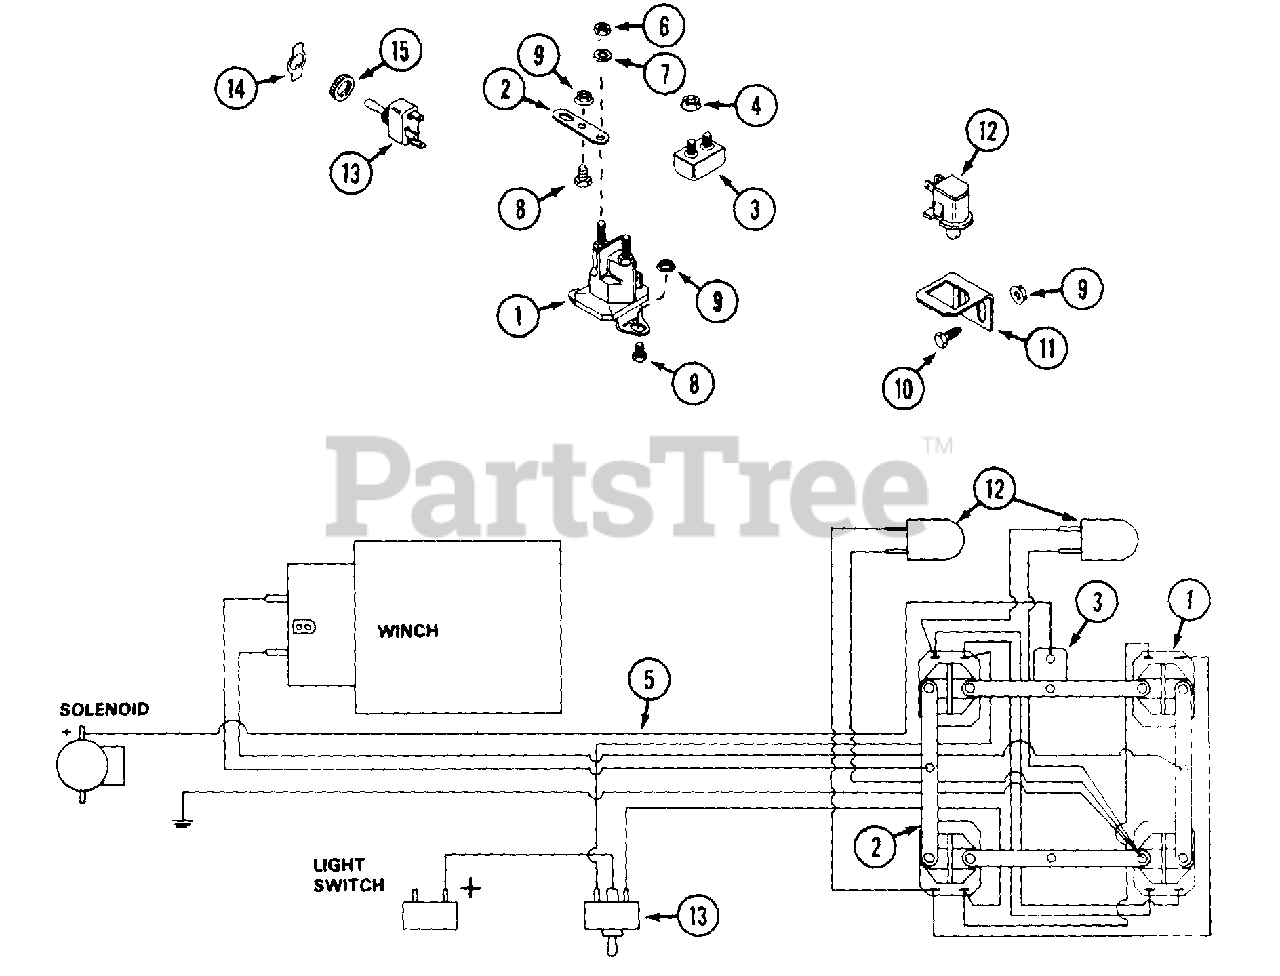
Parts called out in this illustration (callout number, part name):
1	SOLENOID - 12V
2	STRAP
3	BREAKER - 40 amp, 12V
5	HARNESS - wire
6	NUT - 1/4"-20
7	LOCKWASHER - 1/4"
8	BOLT - 1/4"-20 x 1/2"
9	NUT - 1/4"-20 flange
10	BOLT - 1/4"-20 x 3/4"
11	BRACKET - switch
12	SWITCH - limit
13	SWITCH - lift
14	DECAL - switch identification
15	NUT - 15/32"-32, switch
